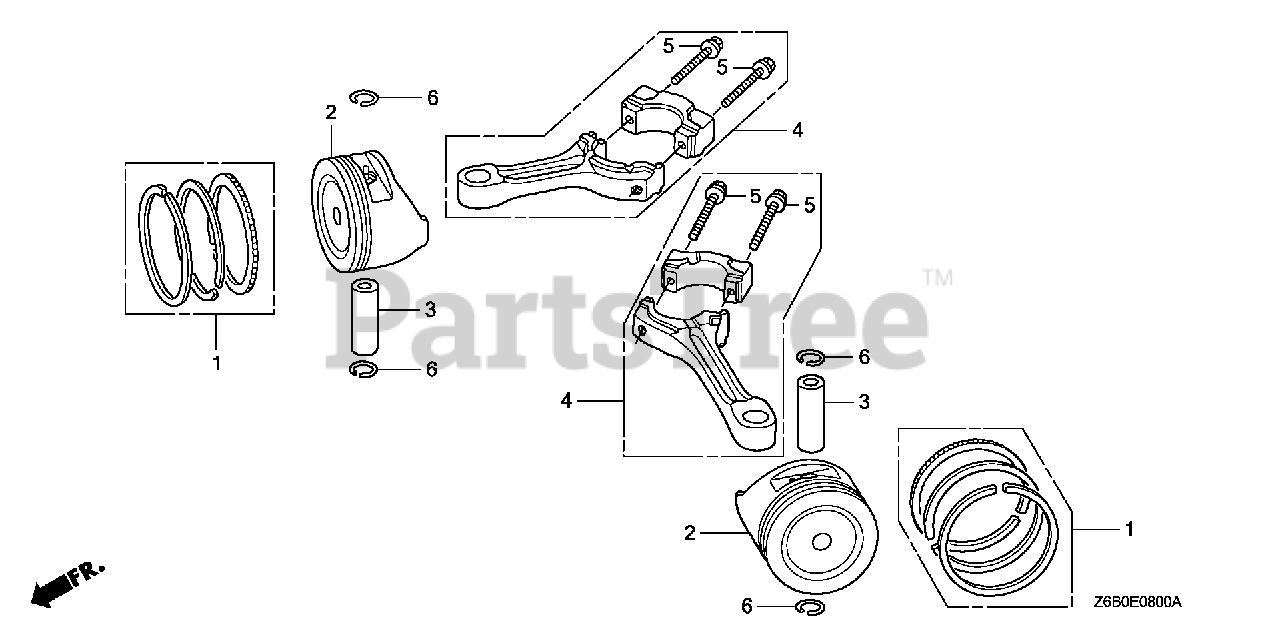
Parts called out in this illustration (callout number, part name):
1	RING SET, PISTON (STD) (NIPPON)
1	RING SET, PISTON
2	PISTON (STD)
3	PIN, PISTON
4	ROD ASSY., CONNECTING
5	BOLT, CONNECTING ROD (6X37)
6	CLIP, PISTON PIN (18MM)
